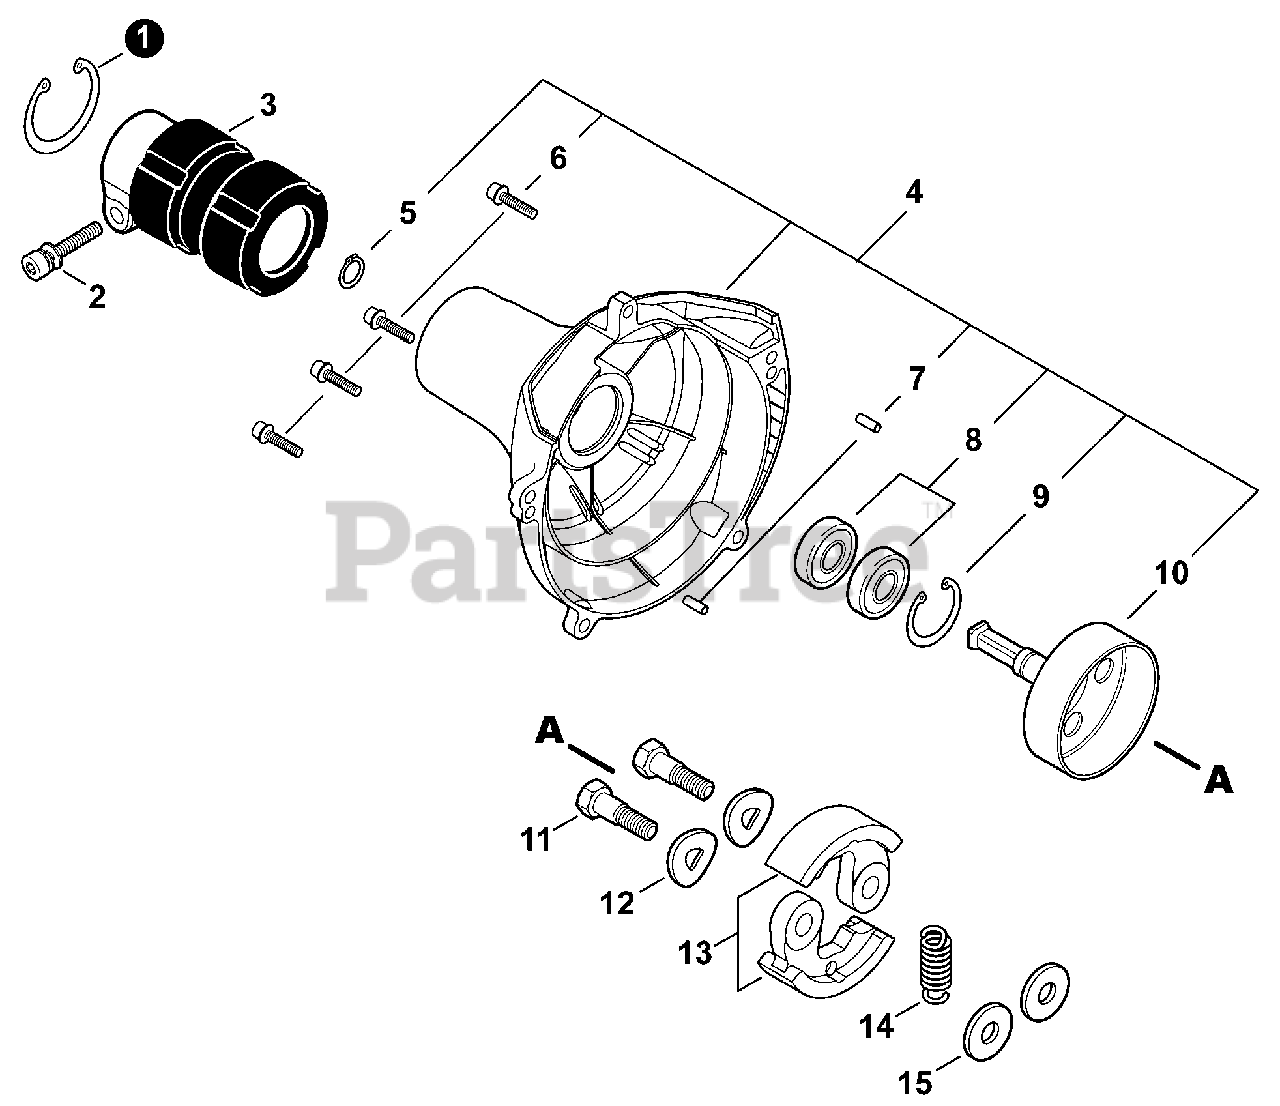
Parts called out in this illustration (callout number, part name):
1	RING, SNAP Ø42
2	BOLT 5×28
3	HOLDER, MAIN PIPE
4	COVER ASSY, FAN
5	RING, RETAINING - 12
6	BOLT 5×20
7	PIN, LOCATING 4×8
8	BEARING, BALL 6001
9	RING, SNAP 28
10	DRUM, CLUTCH
11	BOLT, CLUTCH 8×7.9×M6
12	WASHER, SPRING 8.5×16×0.5
13	SHOE, CLUTCH
14	SPRING, CLUTCH
15	WASHER 6.2×19×1.0
